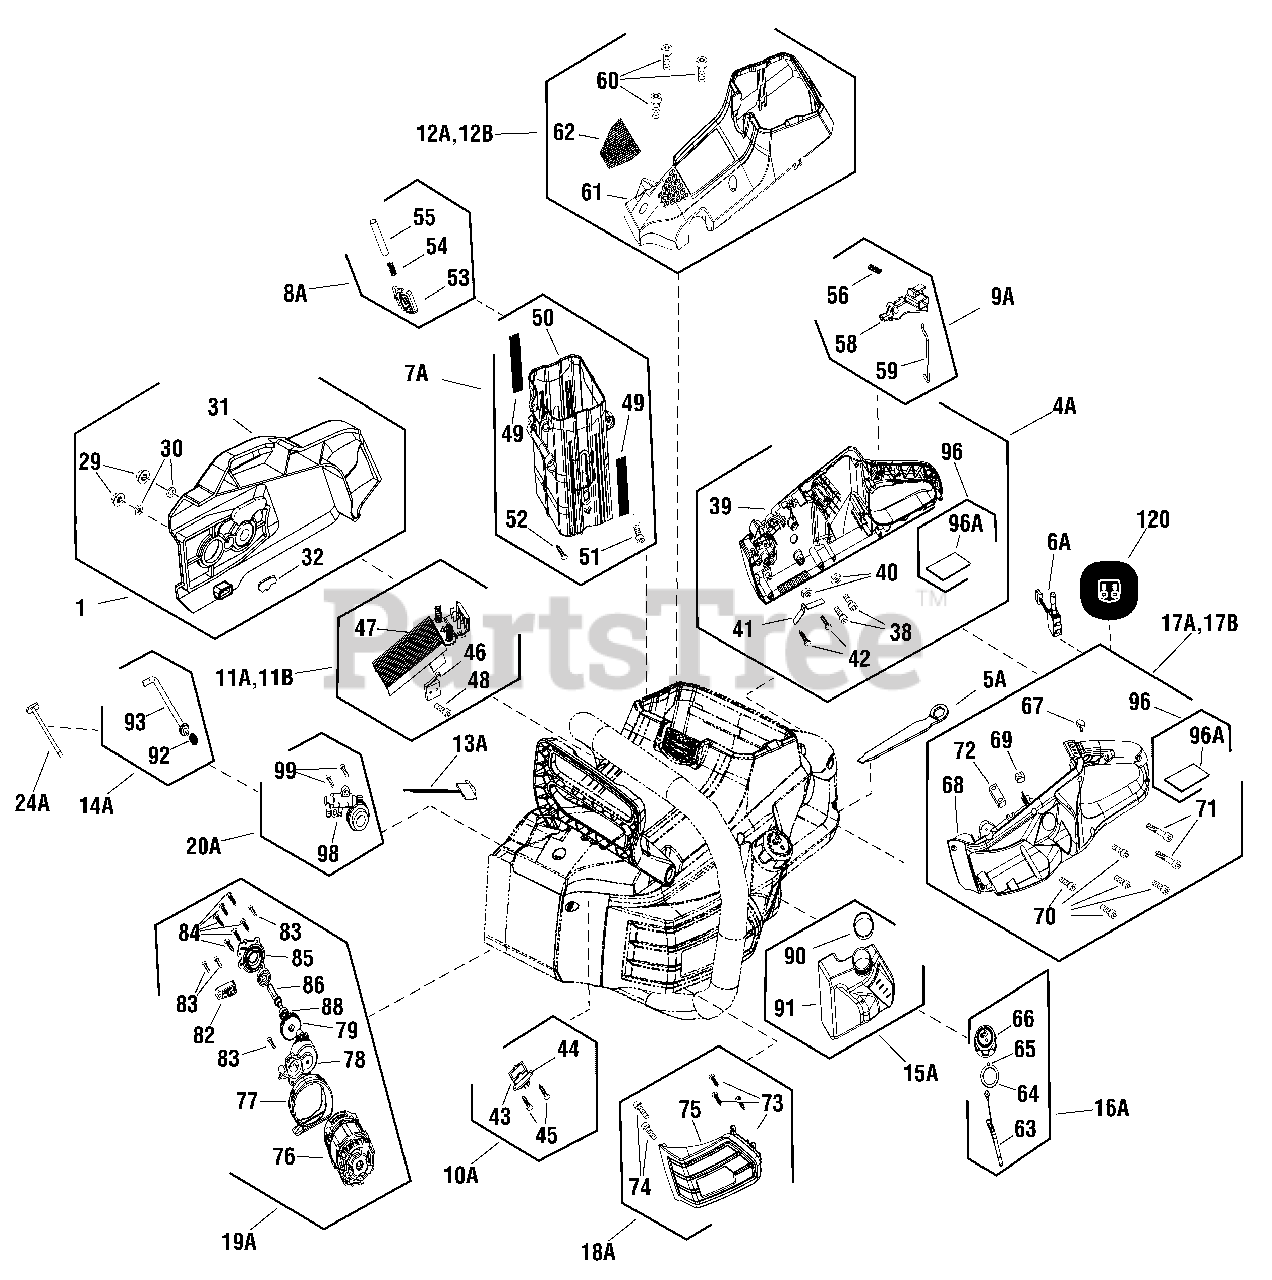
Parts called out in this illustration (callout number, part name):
1	KIT, SIDE COVER ASSEMBLY, NA & EU
4A	KIT, RIGHT HOUSING ASSEMBLY
5A	KIT, SPANNER
6A	KIT, VARIABLE SPEED SWITCH
7A	KIT, BATTERY HOUSING ASSEMBLY
8A	KIT, RELEASE BUTTON ASSEMBLY
9A	KIT, TRIGGER ASSEMBLY, NA & EU
10A	KIT, OUTAGE SWITCH ASSEMBLY
11A	KIT, PCB ASSEMBLY, NA
11B	KIT, PCB ASSEMBLY, AU
12A	KIT, TOP COVER ASSEMBLY, NA
12B	KIT, TOP COVER ASSEMBLY, EU
13A	KIT, PCB
14A	KIT, INPUT TUBE ASSEMBLY
15A	KIT, OIL TANK ASSEMBLY
16A	KIT, OIL TANK CAP ASSEMBLY
17A	KIT, LEFT HOUSING ASSEMBLY, NA
17B	KIT, LEFT HOUSING ASSEMBLY, EU
18A	KIT, MOTOR COVER ASSEMBLY
19A	KIT, MOTOR ASSEMBLY
20A	KIT, OIL VALVE ASSEMBLY
24A	KIT, OUTLET TUBE
29	KIT, NUT ADJUST
30	KIT, BUSHING
31	COVER, SIDE
32	WASHER
38	SCREW
39	HOUSING, Right
40	NUT
41	LEAF SPRING
42	SCREW
44	BRACKET
45	SCREW
47	PCB
48	SCREW
49	SCREEN, Dust
50	HOUSING, Battery
51	SCREW
52	SCREW
53	BUTTON, Battery Releasee
54	SPRING
55	PIN
56	SPRING
58	BUTTON, LOCK-OFF
59	ROD, CONNECTING
60	SCREW
61	TOP COVER
62	TOP COVER INSERT
63	OIL CAP CORD
64	SEAL RING
65	ELEMENT, FILTER
66	OIL CAP
67	BUTTON, Start
68	HOUSING, Left
69	NUT
70	SCREW
71	SCREW
72	BRACKET
73	SCREW
74	SCREW
75	COVER, MOTOR
76	MOTOR
77	CHANNEL, AIR OUTLET
78	HOUSING, GEAR BOX
79	GEAR, Drive
82	BRACKET
83	SCREW
84	SCREW
85	LABEL
86	SHAFT
88	BEARING
90	SEAL RING
91	TANK, OIL
92	SPRING
93	TUBE, INPUT
96	KIT, PROTECTIVE COVER DECAL, CLEAR
96A	KIT, PROTECTIVE COVER DECAL, CLEAR
96A	PROTECTIVE COVER DECAL, CLEAR
98	OIL VALVE
99	SCREW
120	DECAL, XD POWER WARNING
